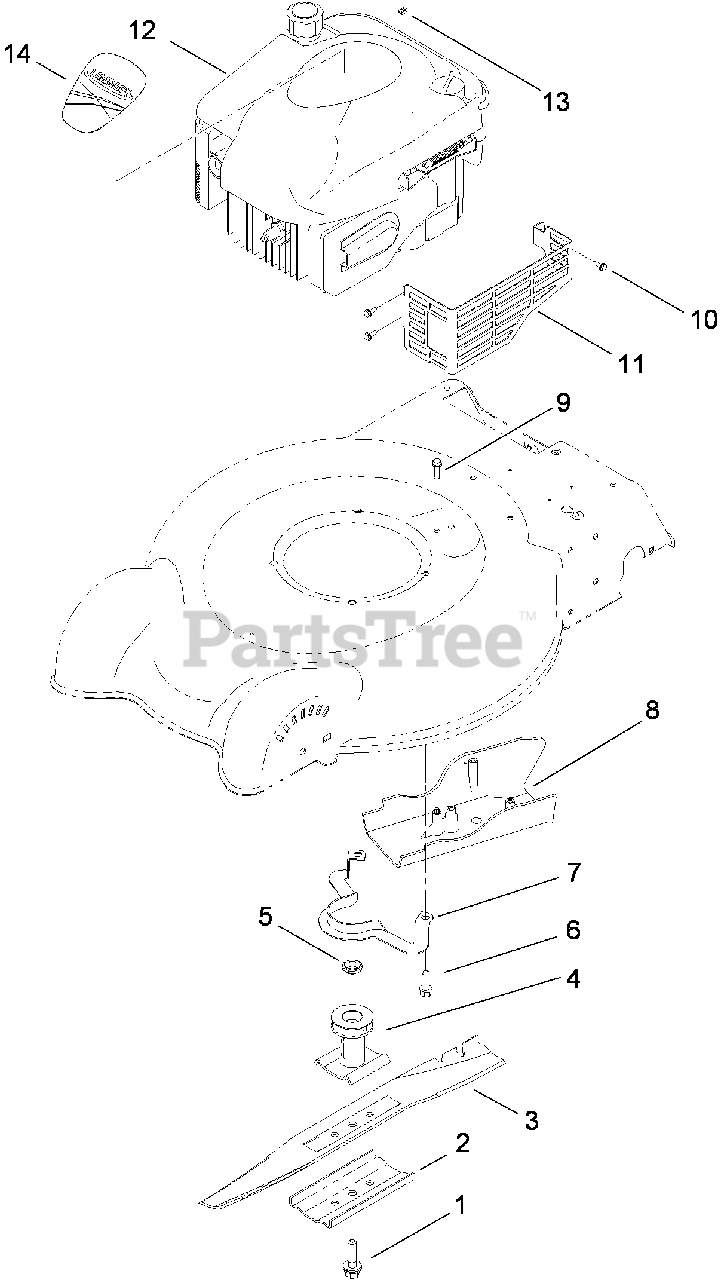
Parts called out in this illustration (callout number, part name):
1	BOLT-BLADE
2	SUPPORT-BLADE
3	BLADE-20 INCH
4	BLADE DRIVER ASM
5	Spacer-Driver
6	SCREW-TAPTITE
8	COVER-BELT
9	SCREW-HWH
10	SCREW-TAPTITE
11	SHIELD-MUFFLER
13	STOP-ROPE
14	DECAL-SHROUD
